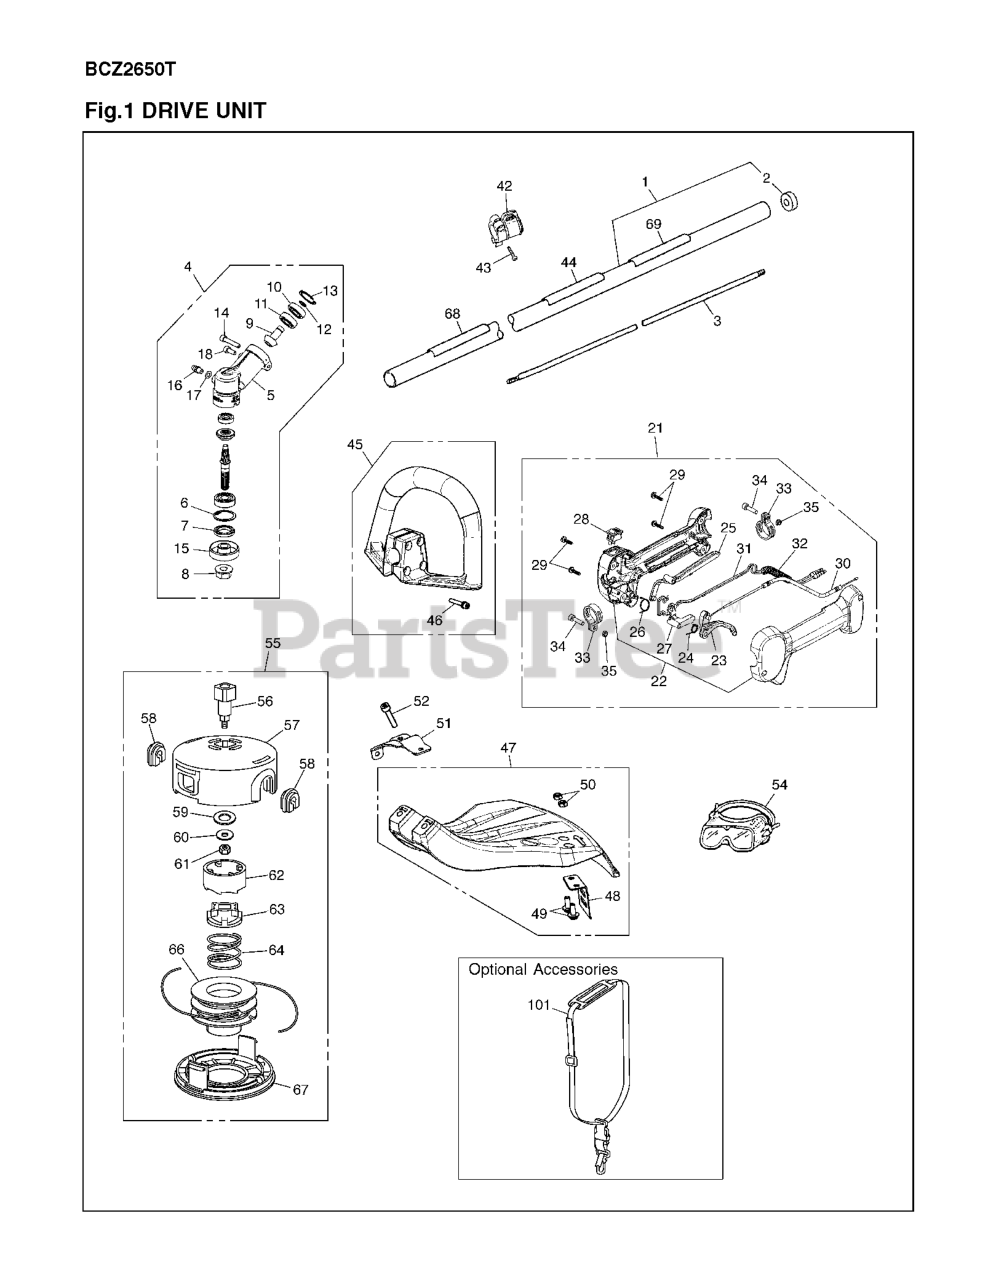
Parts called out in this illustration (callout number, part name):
1	PIPE COMP
4	GEAR CASE ASSY
5	GEAR CASE
6	RING,SNAP M26x1.2 RP-318013340
7	SEAL, OIL(RPLS 3565-13131)
13	RP_RING
14	BOLT TORX
15	HOLDER-A
16	FITTING, GREASE
18	BOLT, TORX
21	GRIP-A
22	GRIP HALF SET
23	LEVER, THROTTLE
24	SPRING, THROTTLE
25	%LEVER SAFETY
27	LEVER, JOINT
31	CORD - C
34	SCREW
35	NUT
42	HANGER COMP.
44	PLATE, NAME
45	HANDLE ASSY. (RPLS T319514001)
47	GUARD ASSY
52	BOLT, TORX
54	GOGGLExxx (RPLS
55	TAP HEAD COMPLETE
56	SHAFT BOLT
57	HOUSING
58	Eyelet Kit, 2-Pack
59	Flat Washer
60	FLAT WASHER
61	Lock Nut
62	CAM FOLLOWER
63	INNER CAM
67	BOTTOM COVER
68	LABEL CAUTON FOR BC
69	CAUTION LAEL
101	STRAP ASSY
